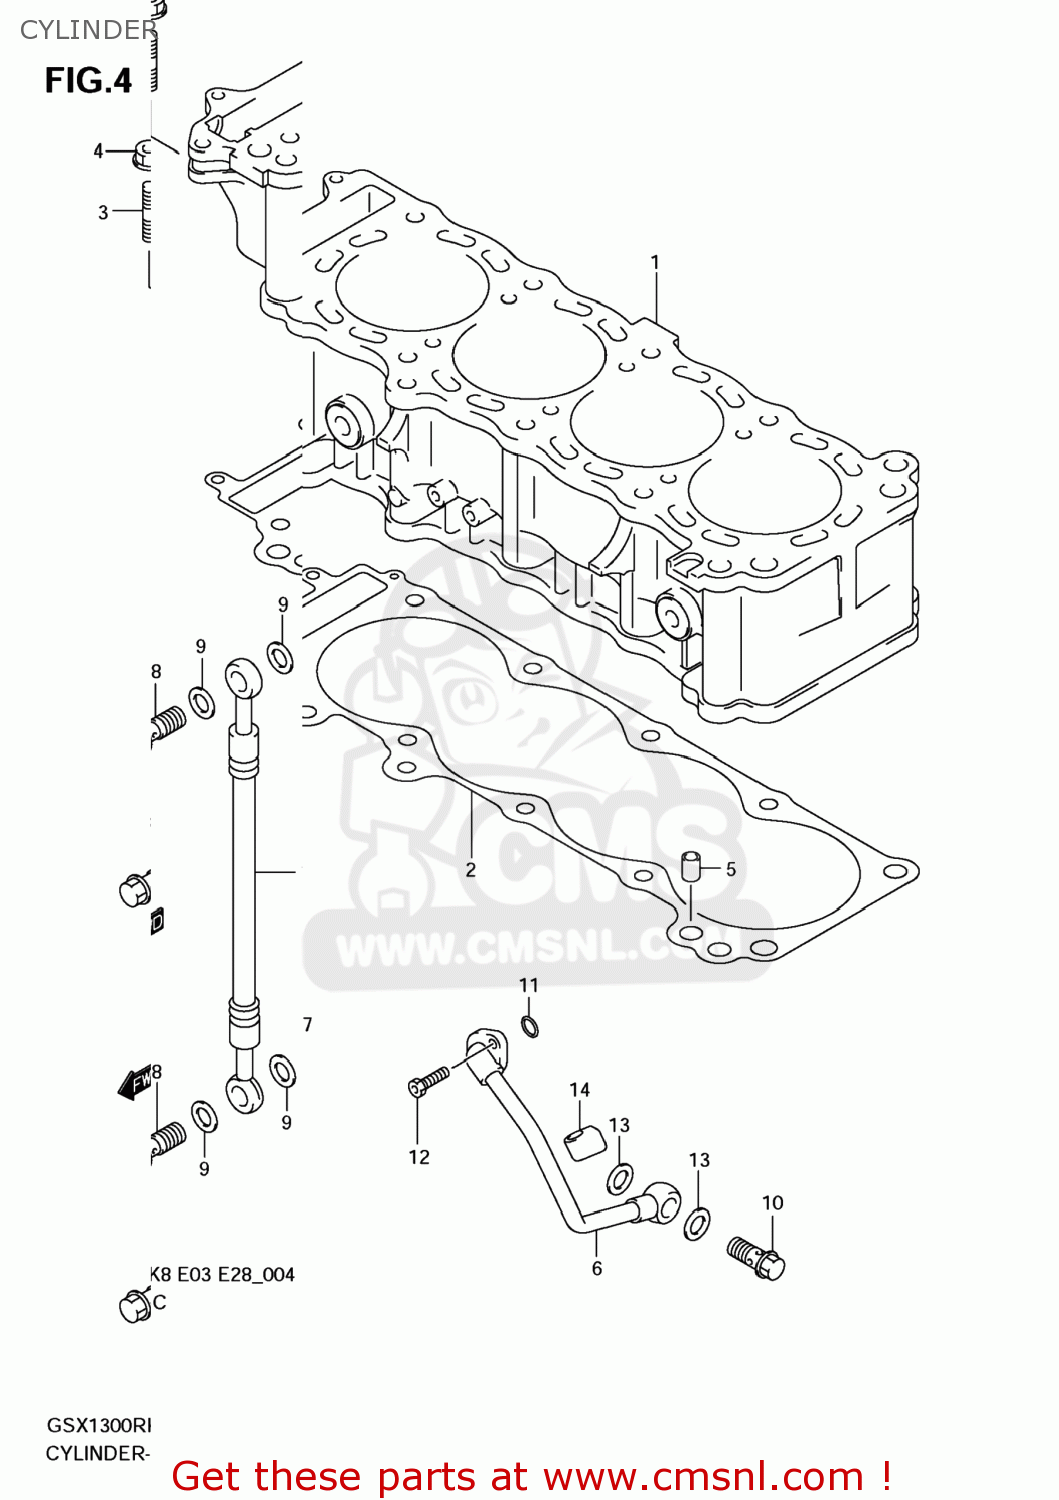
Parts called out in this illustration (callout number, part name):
1	CYLINDER
2	GASKET,CYLINDER (NAS)
3	BOLT,STUD
4	NUT
5	PIN
6	PIPE,CRANKCASE OIL
7	HOSE,CYLINDER HEAD OIL
8	BOLT UNION
9	GASKET(10.1X16X1) (NAS)
10	BOLT UNION
11	O RING(D:2.4,ID:11.8)
12	BOLT(6X16)
13	GASKET(14X20X1.5) (NAS)
14	CUSHION,CRANKCASE DIL PIPE
